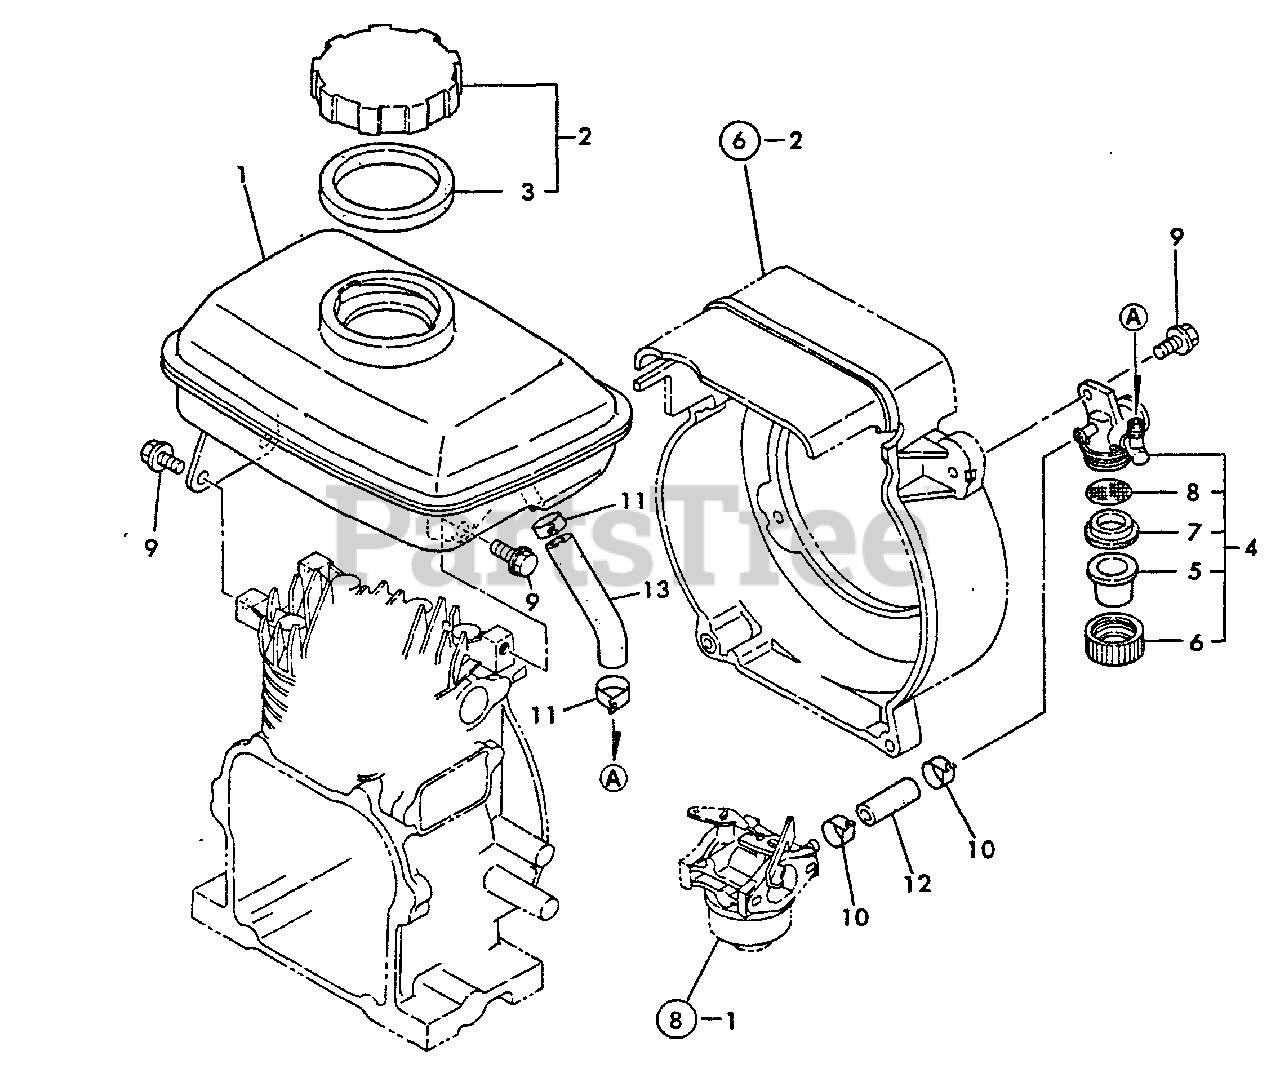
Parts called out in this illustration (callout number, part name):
1	FUEL TANK ASSY
2	CAP ASSY
3	GASKET
4	FUEL COCK ASSY
5	BOWL, STRAINER
6	RETAINER
7	GASKET
8	STRAINER, FUEL
9	BOLT - 6X8 -- PLATED
10	CLAMP, HOSE - 9
11	CLAMP, HOSE
12	PIPE - FUEL
13	PIPE - FUEL
